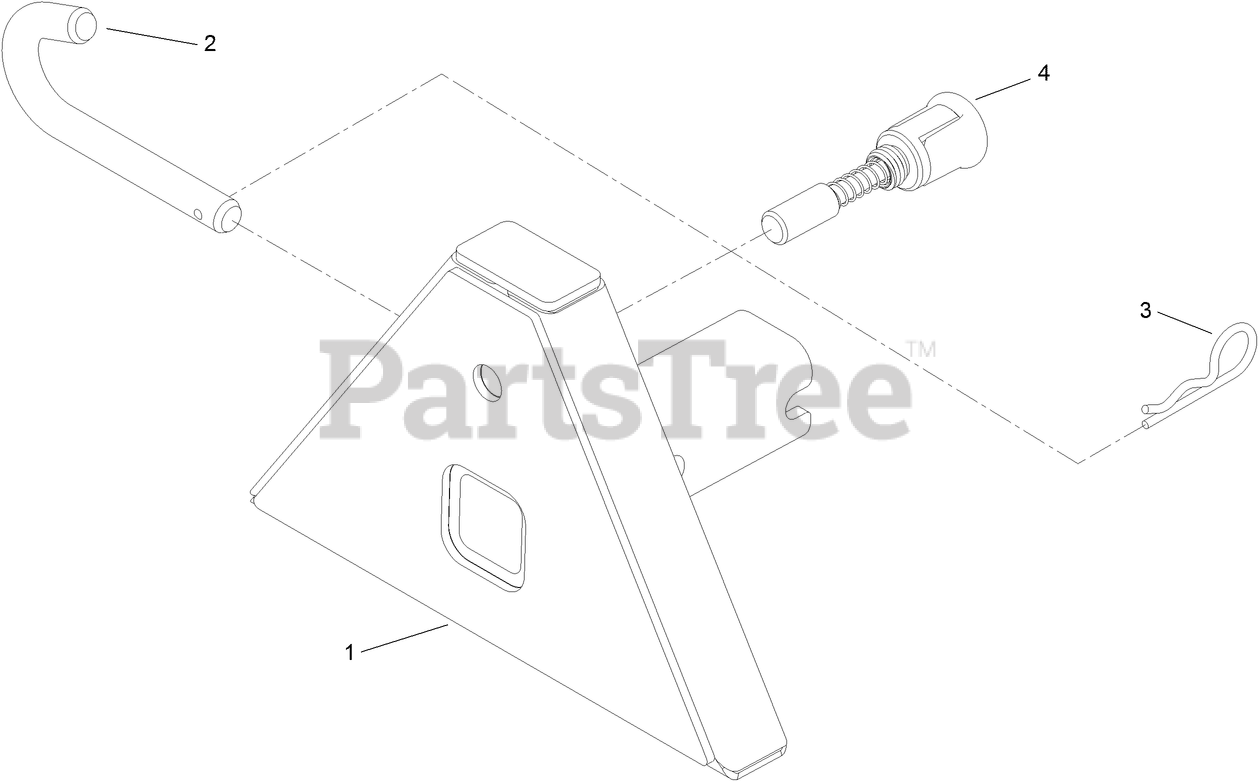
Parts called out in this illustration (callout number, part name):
1	TRIANGLE
2	PIN-ATTACH
3	PIN-HAIR
4	PIN-SPRING
